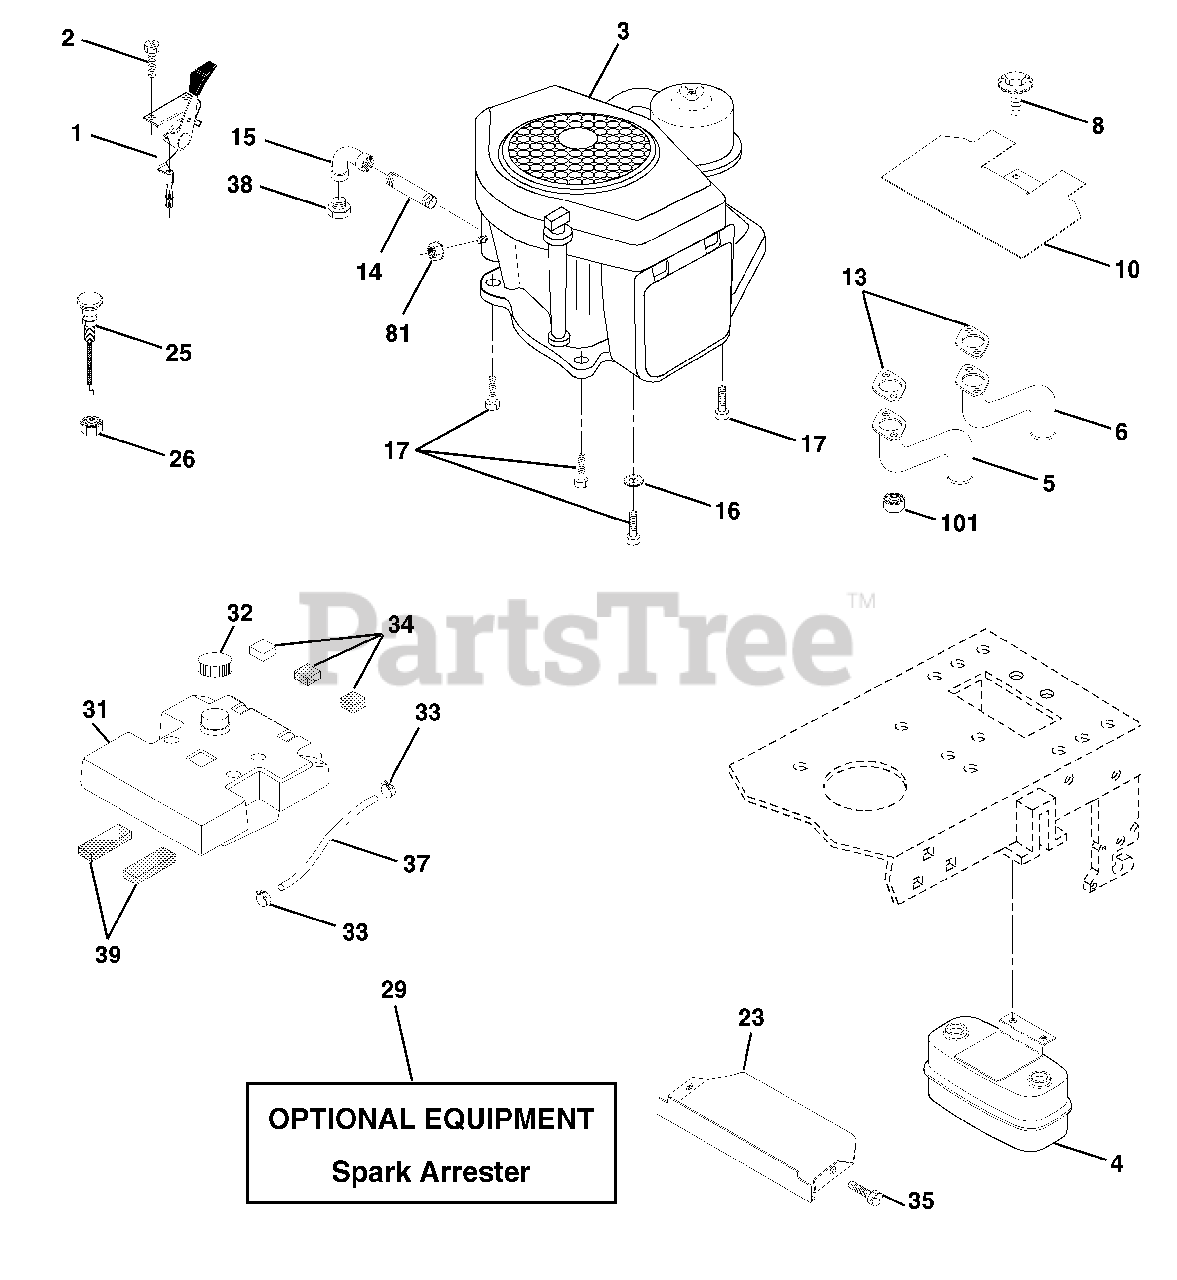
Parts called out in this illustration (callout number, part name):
1	Control Throt Flg 180 LH
2	Screw Hex Thd Cut 1/4-20x5/8 T
4	Muffler Asm Twin Lo-Tone
5	Pipe Exhaust CV18/20 LH
6	Pipe Exhaust CV18/20 RH
7	Clip, Fuel Line
8	Bolt 5/16-18unc x 3/4 W/Sems
10	Shield Heat Muffler CV18/20
13	Gasket Kohler CV18-CV26
14	Nipple Pipe 3/8 Npt X 4-1/2"
15	Elbow Std 90 Degree 3/8-18 Npt
16	Washer Lock Ext Tooth 3/8
17	Screw Thdrol 3/8-16 x 1-1/2
23	Shield Browning
25	Choke Control 37"
26	Nut, Keps 3/8-24 Unf
29	Kit Spark Arrestor (Flat Scrn)
31	Tank Fuel 3 50 Rear
32	Cap Asm Fuel Top N/Lany Vented
33	Clamp Hose Blk
34	Pad, Spacer
35	Screw Thdrol 5/16-18 x 3/4
37	Line Fuel 7.5
38	Plug Oil Drain
39	Pad, Idler
40	Bushing
41	Stem Tank Fuel
81	Nut Flange 1/4-20 Starter Nut
101	Nut Flange M8-1.25 Non-Lk Zinc
